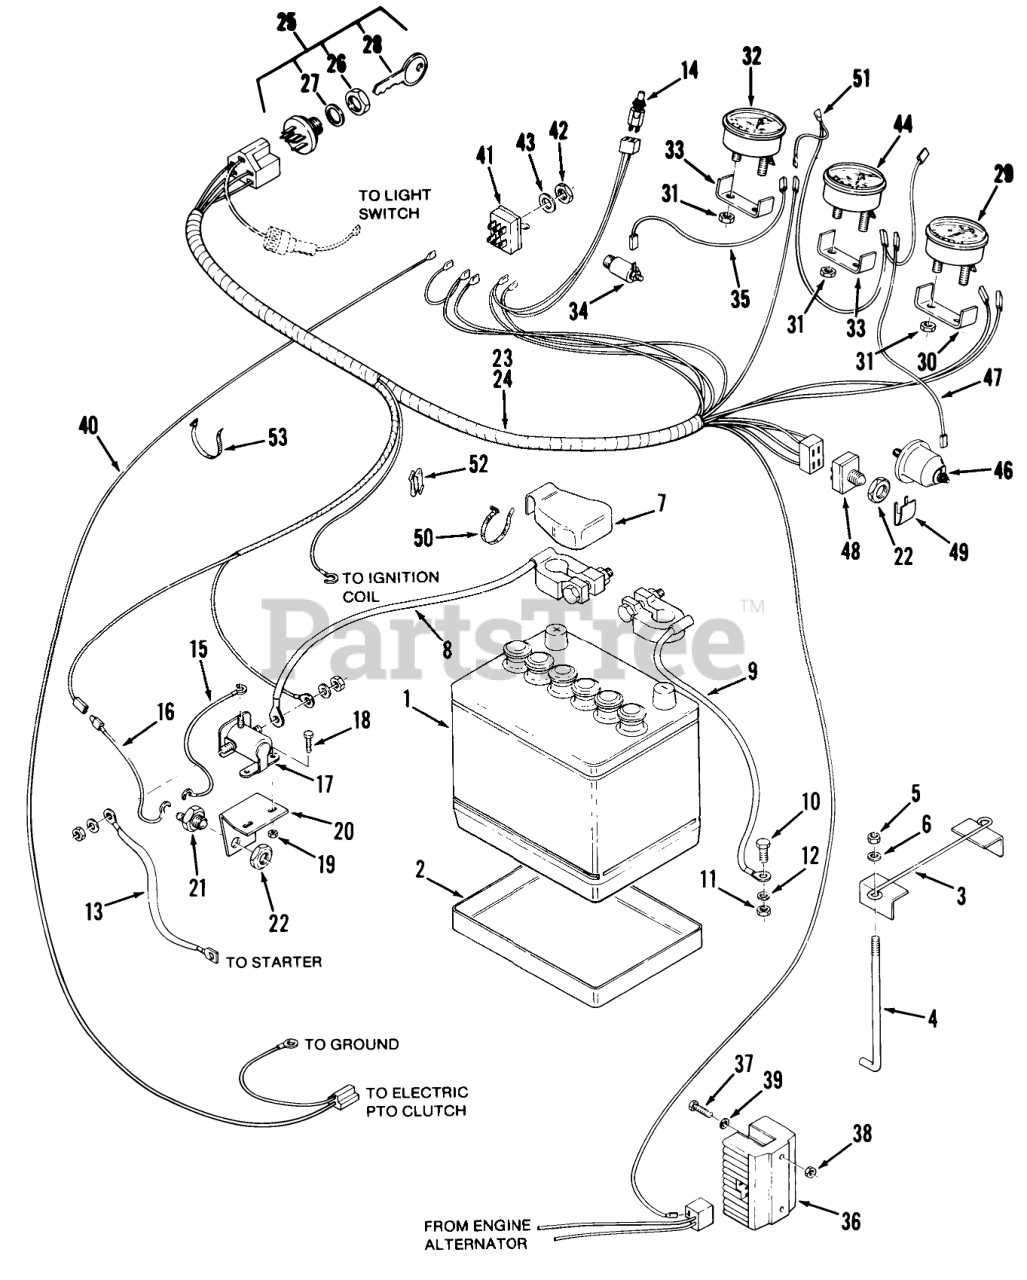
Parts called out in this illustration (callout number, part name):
1	Battery
2	Battery Box
3	Assy-Hold Down
4	Hook-Battery Retainer
5	Nut
7	COVER-REWORK 516333
8	ASSY-WIRE SOLENOID
9	ASSY-WIRE
10	Bolt
11	Nut
12	WASHER 5/16 SAE
13	Cable
14	SWITCH
15	WIRE ASSY
16	Assy-Wire
17	Solenoid
18	Bolt
19	Nut
20	Bracket
21	SWITCH SAFETY
22	NUT-SPECIAL 9/16-18
23	Wiring Harness
24	Wiring Harness
25	SWITCH-IGNITION
27	LOCKWASHER
28	Key-EL
29	AMMETER W/CLAMP
30	Clamp
31	HEX NUT 10-32 E.S.
32	Gauge-Oil Temp
33	CLAMP MOUNTING
34	Assy-Thermistor
35	Assy-Wre
36	REGULATOR-RECTIFIER
37	Bolt
38	Nut
40	Assy-Wire and Plug
41	SWITCH CLUTCH
42	NUT-HEX
43	Nut, Knurled
44	Gauge-Oil Pressure
46	SENDER-OIL PRESSURE
47	Assy-Wire Sender
48	SWITCH-CLUTCH
49	CLIP-SWITCH
50	PLASTIC TIE
51	Assy-Wire Gauge
52	Clip
53	PLASTIC TIE
